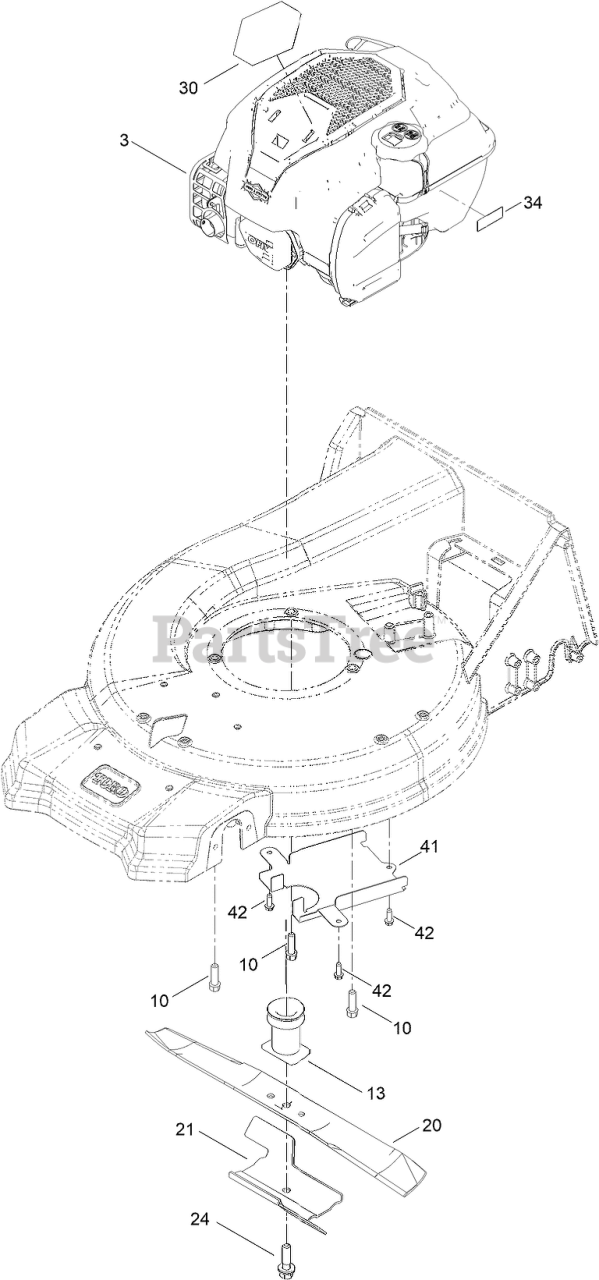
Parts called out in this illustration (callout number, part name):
13	DRIVER-BLADE
20	BLADE-21IN, RECYCLING
21	ACCELERATOR-BLADE
24	BOLT-BLADE
30	DECAL-BRIGGS 725 EXI SS
34	DECAL-LEVEL, FUEL
41	COVER-BELT, BOTTOM
42	SCREW-HWHTF
